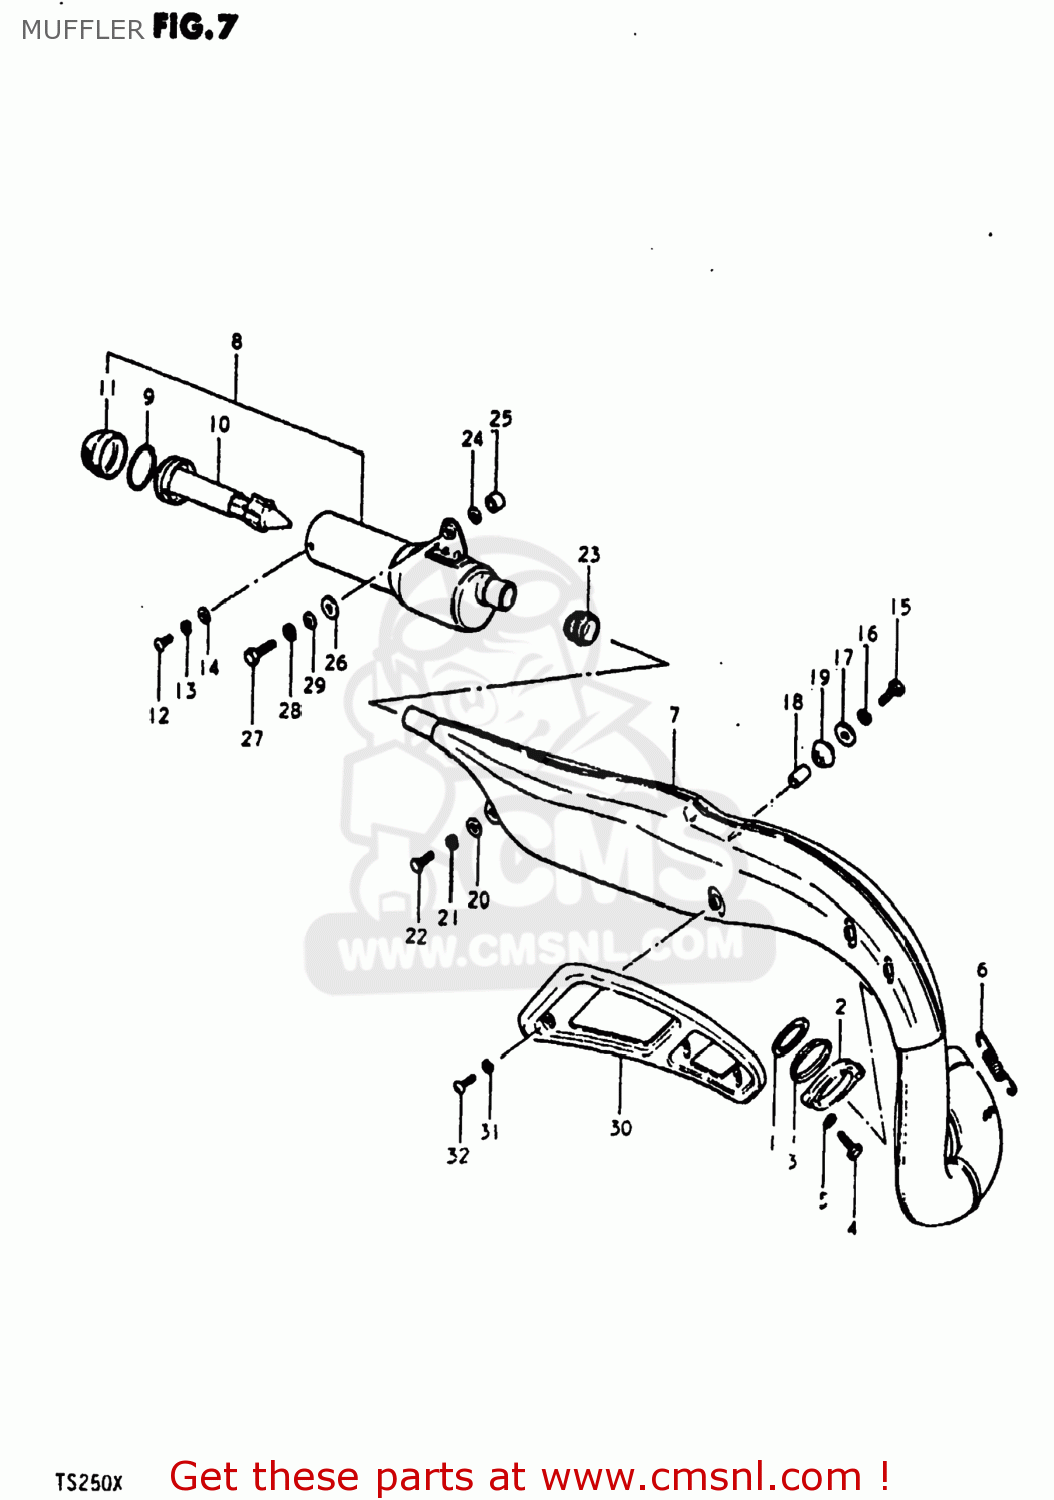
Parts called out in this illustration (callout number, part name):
1	GASKET,EXHAUST PIPE (NAS)
2	CLAMP,EXHAUST PIPE
3	GASKET,EXHAUST PIPE
4	BOLT
5	LOCK WASHER
6	SPRING
7	BODY,MUFFLER
8	MUFFLER ASSEMBLY
9	O-RING (D:3.5 ID:54.4)
10	TUBE,MUFFLER CLEAN OUT
11	COVER,SECOND MUFFLER TAIL
12	SCREW(6X8)
13	WASHER,LOCK
14	WASHER
15	BOLT (8X30)
16	WASHER (8.7X22X2)
17	SPACER (8X12X15)
18	DAMPER,MUFFLER,FR
19	LOCK WASHER
20	WASHER
21	LOCK WASHER
22	BOLT
23	CONNECTOR,MUFFLER
24	WASHER
25	SPACER
26	CUSHION
27	BOLT
28	LOCK WASHER
29	WASHER
30	COVER,MUFFLER
31	LOCK WASHER
32	SCREW
